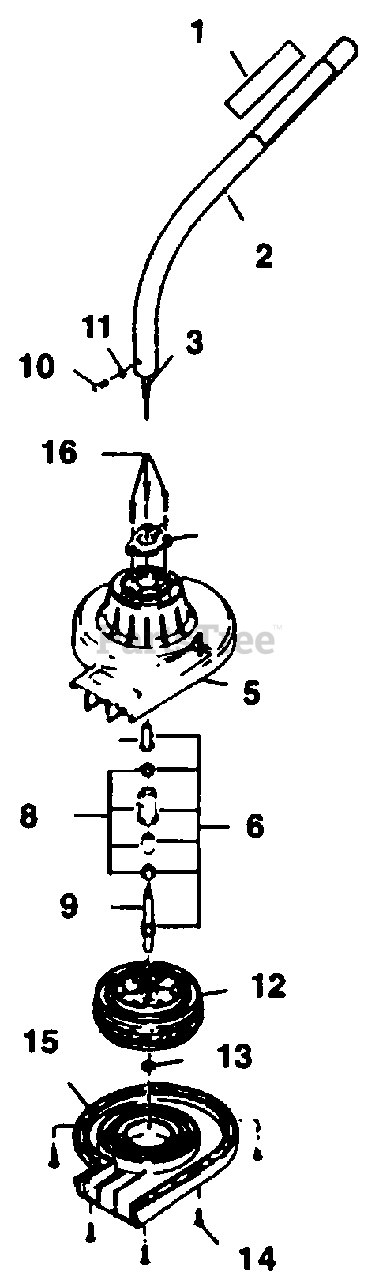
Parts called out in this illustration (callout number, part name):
1	DRIVE SHAFT HOUSING
2	Decal, Warning
3	Flex Cable
5	UPPER HOUSING
6	BEARING HOUSING
8	Arbor Busing Assy
9	Arbor Shaft
14	SCREW
15	LOWER HOUSING
16	SCREW
